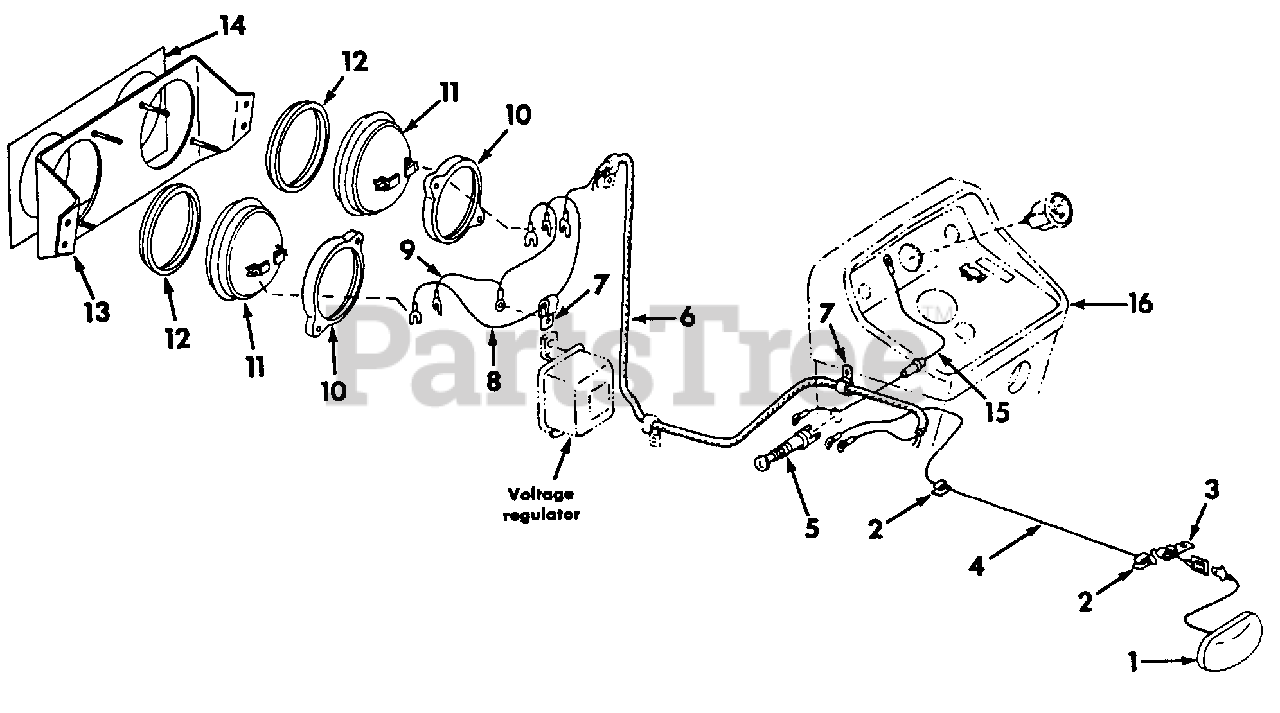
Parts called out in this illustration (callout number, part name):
1	Taillight Assy
2	Clip, Taillight Cable
3	Clip, Lighting Switch to Taillight Cable
4	Cable Assy, Lighting Switch to Taillight
5	Switch Assy, Lighting
6	Harness Assy, Cable
7	Clip, Headlight Cables
8	Cable Assy, RH Headlight to LH Headlight
9	Cable Assy, Headlight to Ground
10	Ring, Headlight Clamp
11	Unit Assy, Sealed Beam Headlight
12	Ring, Headlight Retaining
13	Panel Assy, Headlight Mounting
14	Product Graphic, Headlight Panel Indicator
15	Cable Assy, Lighting Switch to Charge Indicator
16	Pedestal Assy
